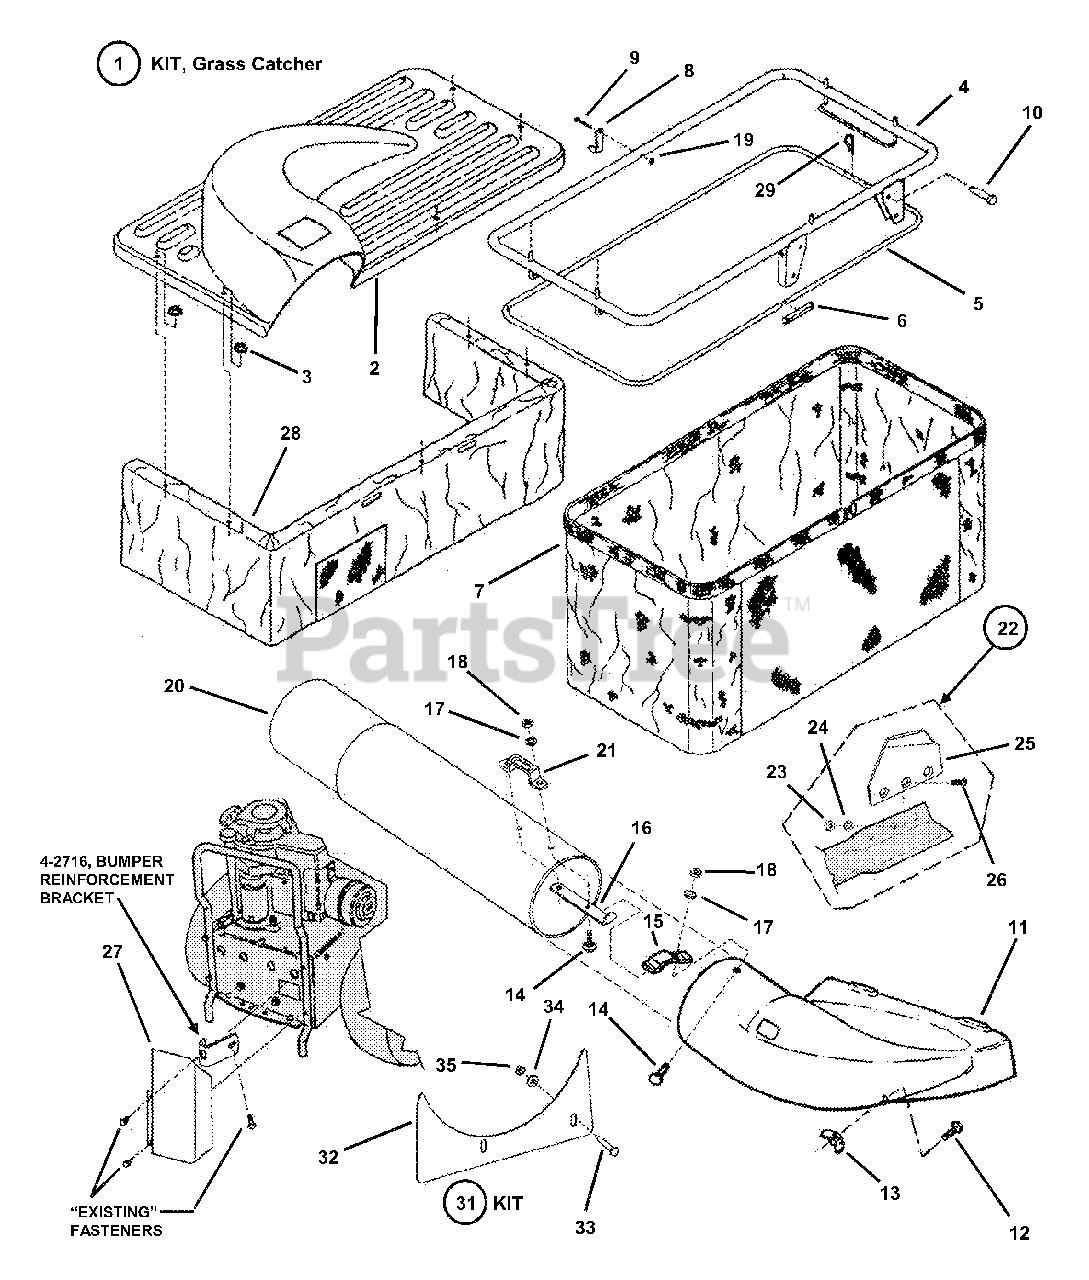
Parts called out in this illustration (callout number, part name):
1	KIT, Grass Catcher (28" & 33") Models
2	TOP, Container
3	WASHER, 5/16" Faceted
4	FRAME, Weldment
5	ROD, Bag
6	CONNECTOR, Bag Rod
7	BAG, Grass
8	LATCH, Top
9	SCREW, #10-32 x 1-3/8" Hex Head Machine
10	PIN, 5/16 x 1-11/16" Clevis
11	ADAPTER, Deck
12	BOLT, 5/16-18 x 1" Short Neck Carriage, Grade 5
13	WING LOCK NUT, 5/16-18
14	BOLT, 1/4-20 x 3/4" Short Neck Carriage, Grade 5
15	LATCH, Tube
16	BASE, Handle
17	WASHER, 1/4 Internal Tooth Lock
18	NUT, 1/4-20 Hex
19	NUT, #10-32 Hex Lock
20	TUBE, Grass (36" long)
21	HANDLE, Tube
22	KIT, Air Lift
23	NUT, 5/16-24 Hex
24	WASHER, 5/16" Internal Tooth Lock
25	AIR-LIFT
26	SCREW, 5-16-24 x 11/16" Machine
27	SHIELD, Muffler Heat (8 HP Engines)
28	DUST SKIRT
29	PIN, 3/32 x 1-1/2" Hair
31	KIT, Catcher Debris Shield
32	SHIELD, Debris
33	BOLT, 1/4-20 x 1-1/2" Hex
34	WASHER, 1/4" Flat
35	NUT, 1/4-20 Hex Top Lock
